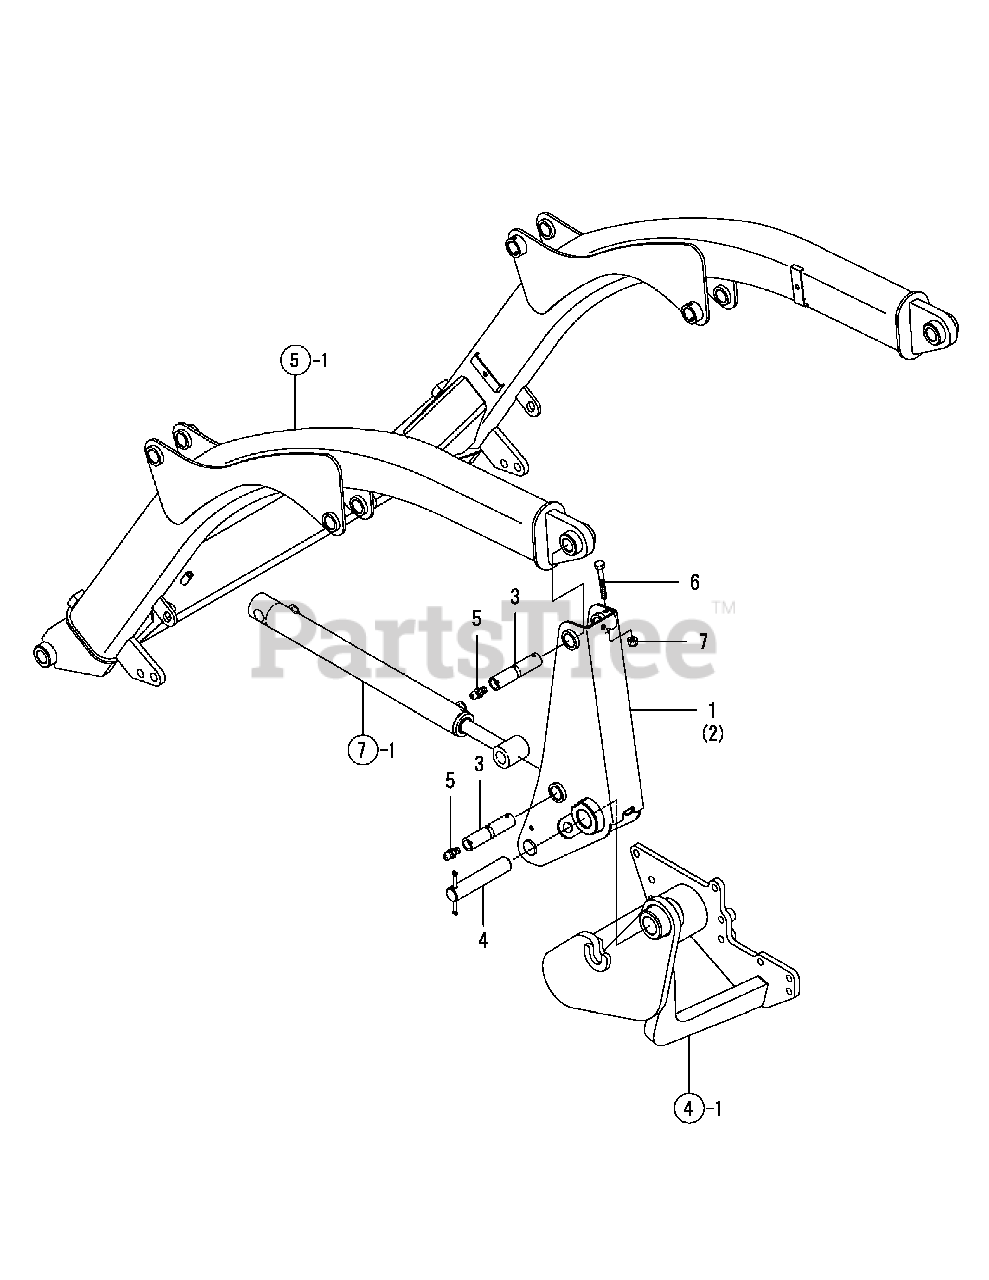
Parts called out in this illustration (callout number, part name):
1	Support PL Assy, L
2	Support PL Assy, R
5	Nipple M6F, Grease
6	Bolt M 6X 50 Plated
